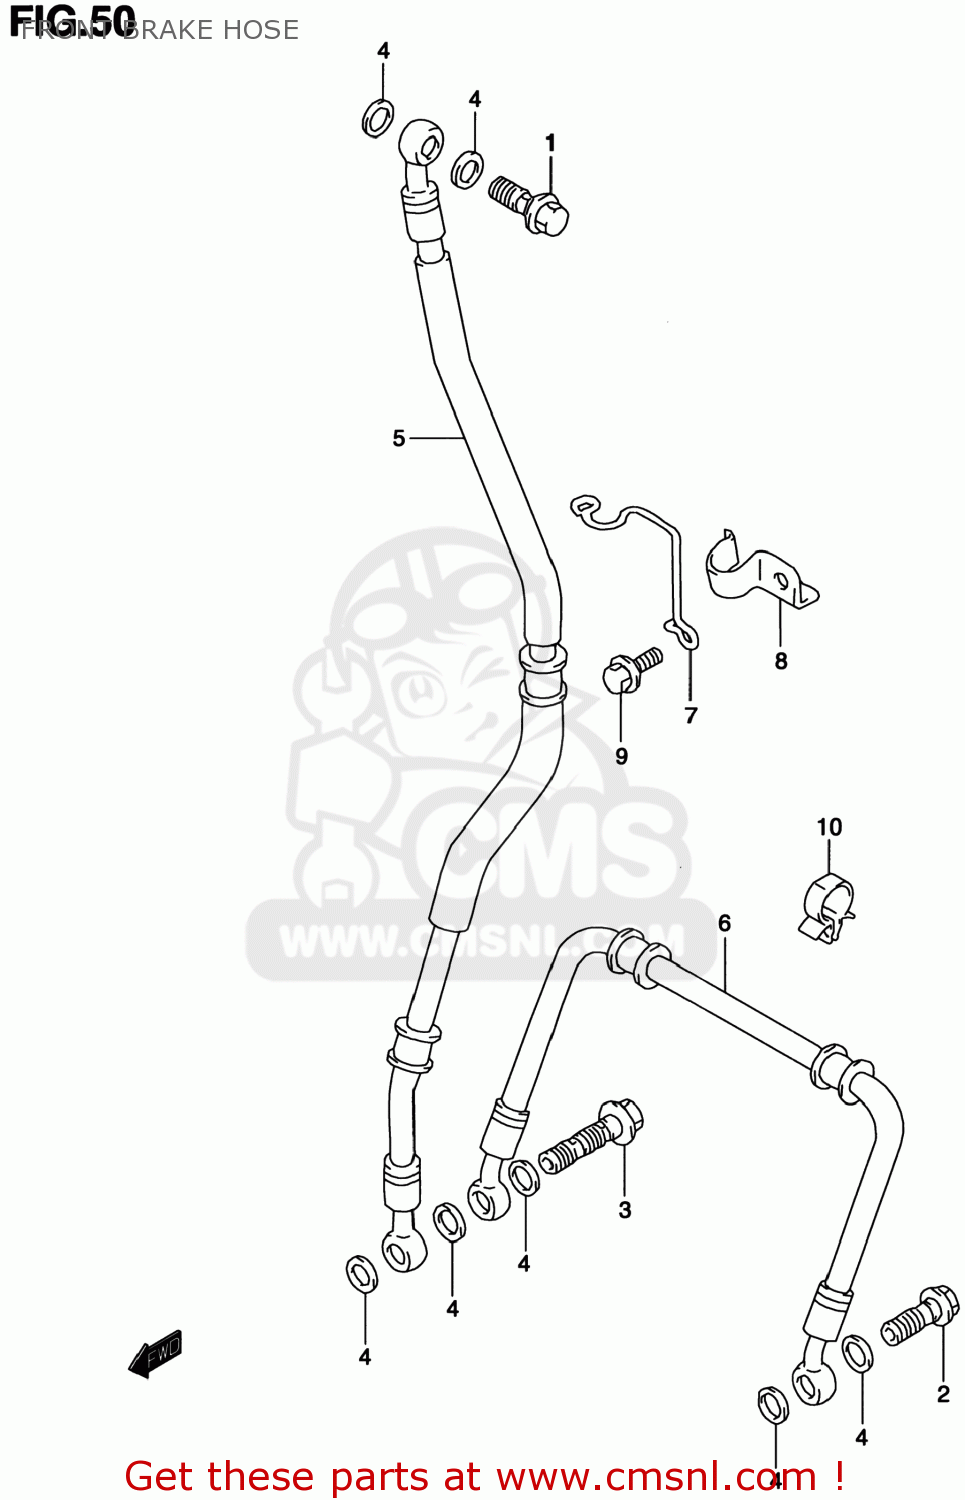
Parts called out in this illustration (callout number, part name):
1	BOLT UNION
2	BOLT UNION
3	BOLT UNION
4	WASHER(10X15X1.5)
5	HOSE,FR BRAKE NO.1
6	HOSE,FR BRAKE NO.2
7	GUIDE,FRONT BRAKE HOSE
8	CLAMP,FR BRAKE HOSE UPR
9	BOLT
10	CLAMP
